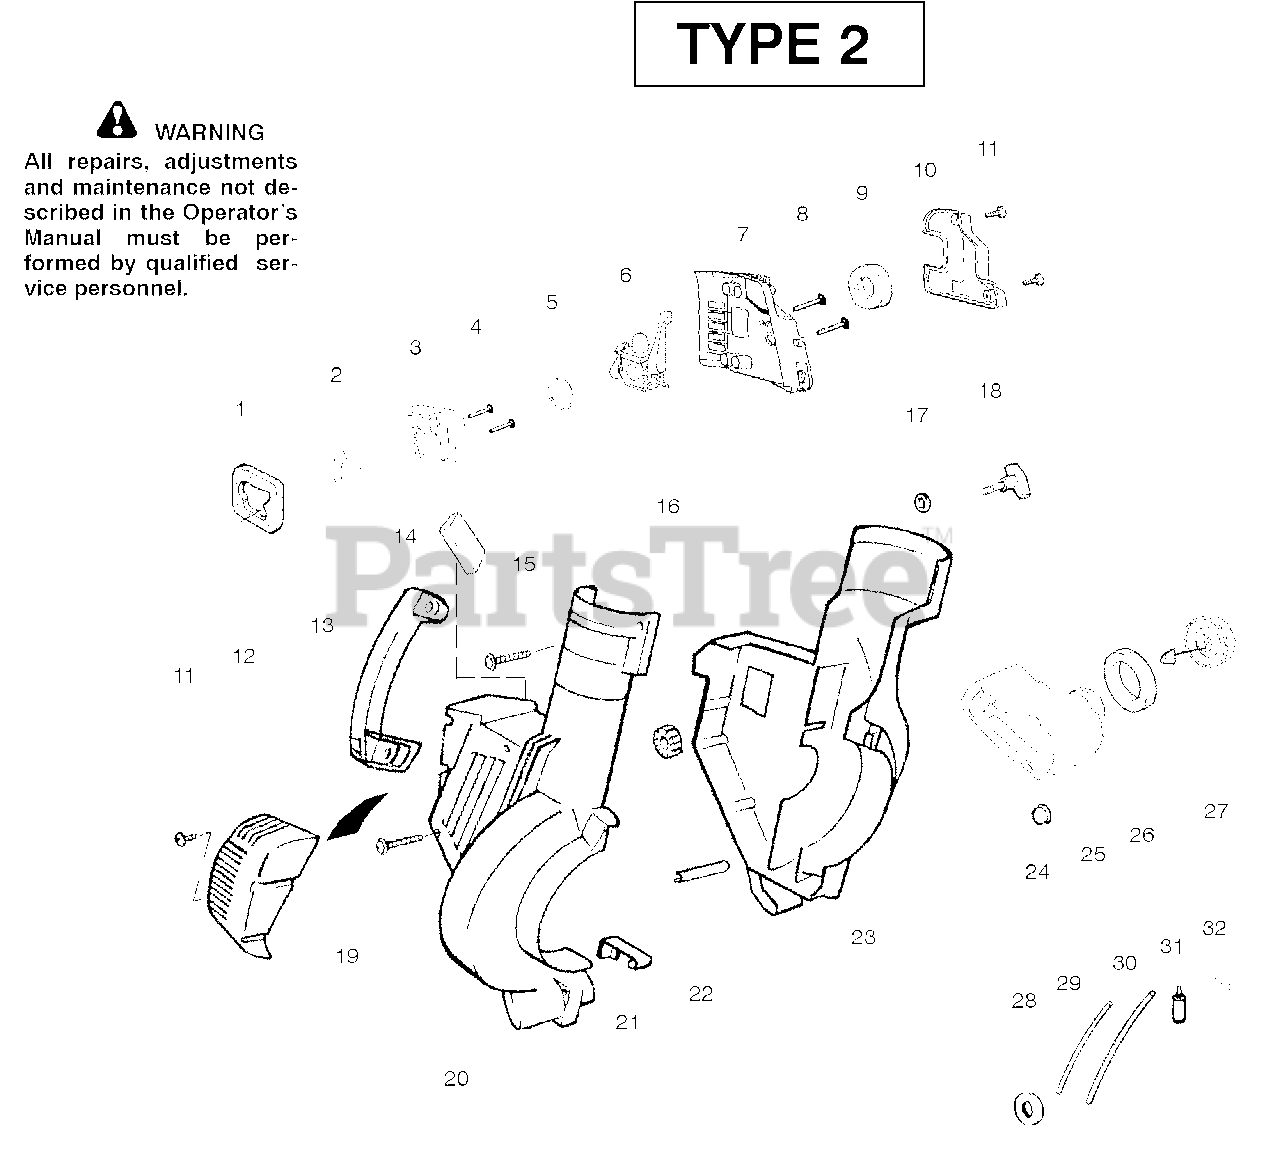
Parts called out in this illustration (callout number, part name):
1	Air Dam (kit)
2	Gasket-Adapter (kit)
3	Carburetor Adaptor
5	Gasket-Carburetor (kit)
6	Kit-Carb Ass'y. (C1Q-W11)
6	Kit-Carb Ass'y. (C1Q-W11C)
10	Cover-Air Filter
12	Guard-Muffler
14	Foam - 71.12mm (kit)
18	Knob-Tube Clamp
19	Reflector-Heat (kit)
20	Housing-Right
21	Spring-Cover Latch
22	Guide-Starter Rope
23	Housing-Left
24	Isolator-Crankcase
25	Assy-Fuel Tank
26	Gasket-Fuel Tank
27	Fuel Cap w/Retainer
28	Grommet-Shroud
29	Kit-Line Carb/Purge
30	Kit-Line Tank/Purge
31	Assy-Fuel Pick-up
32	Grommet-Fuel line (kit)
